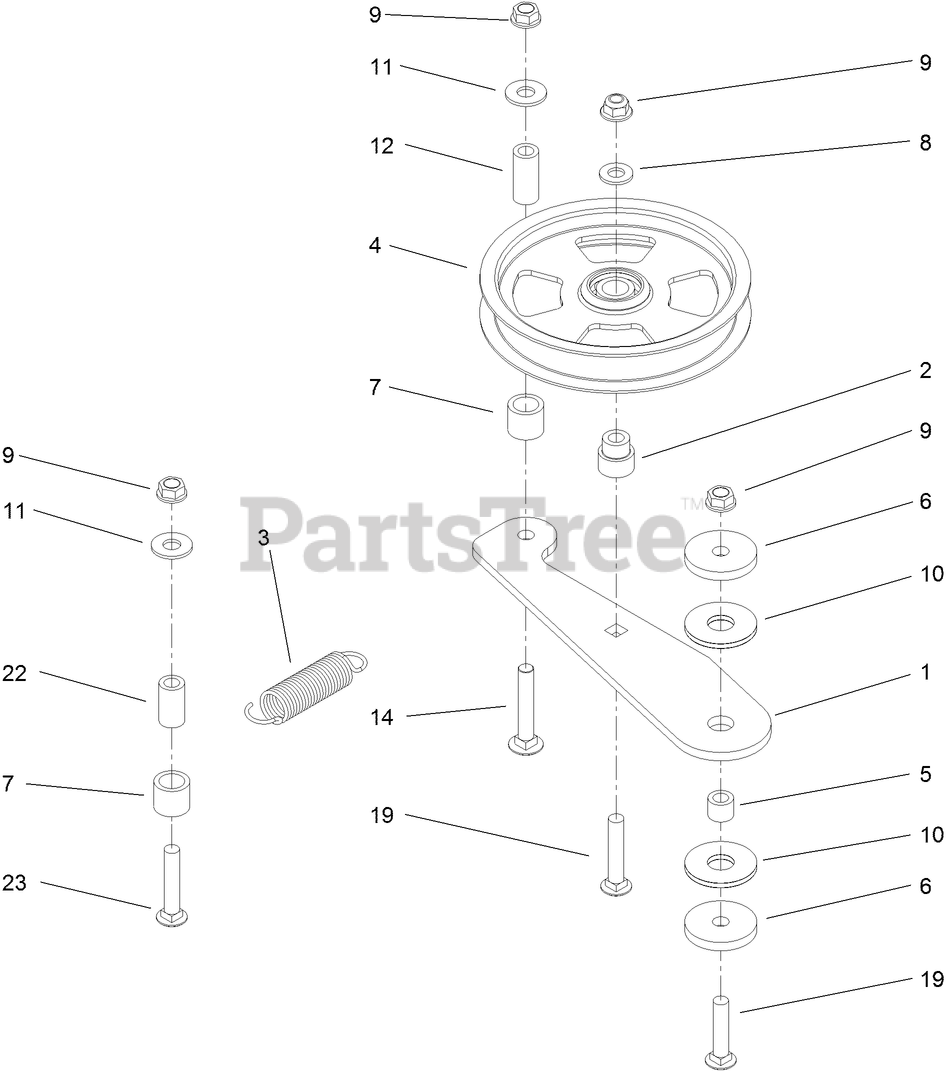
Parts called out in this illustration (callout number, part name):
1	ARM-IDLER
2	BUSHING-IDLER
3	SPRING-EXTENSION
4	PULLEY-IDLER, FLAT
5	BUSHING-LEVER, LIFT
6	WASHER-PLAIN
7	SPACER-RUBBER
8	WASHER-FLAT
9	NUT-HF, NI
10	WASHER-FRICTION, COMPOSITE
11	WASHER-FLAT
12	SPACER
14	SCREW-CARR
19	SCREW-CARR
22	SPACER
23	BOLT-CARR, SHORT NECK
